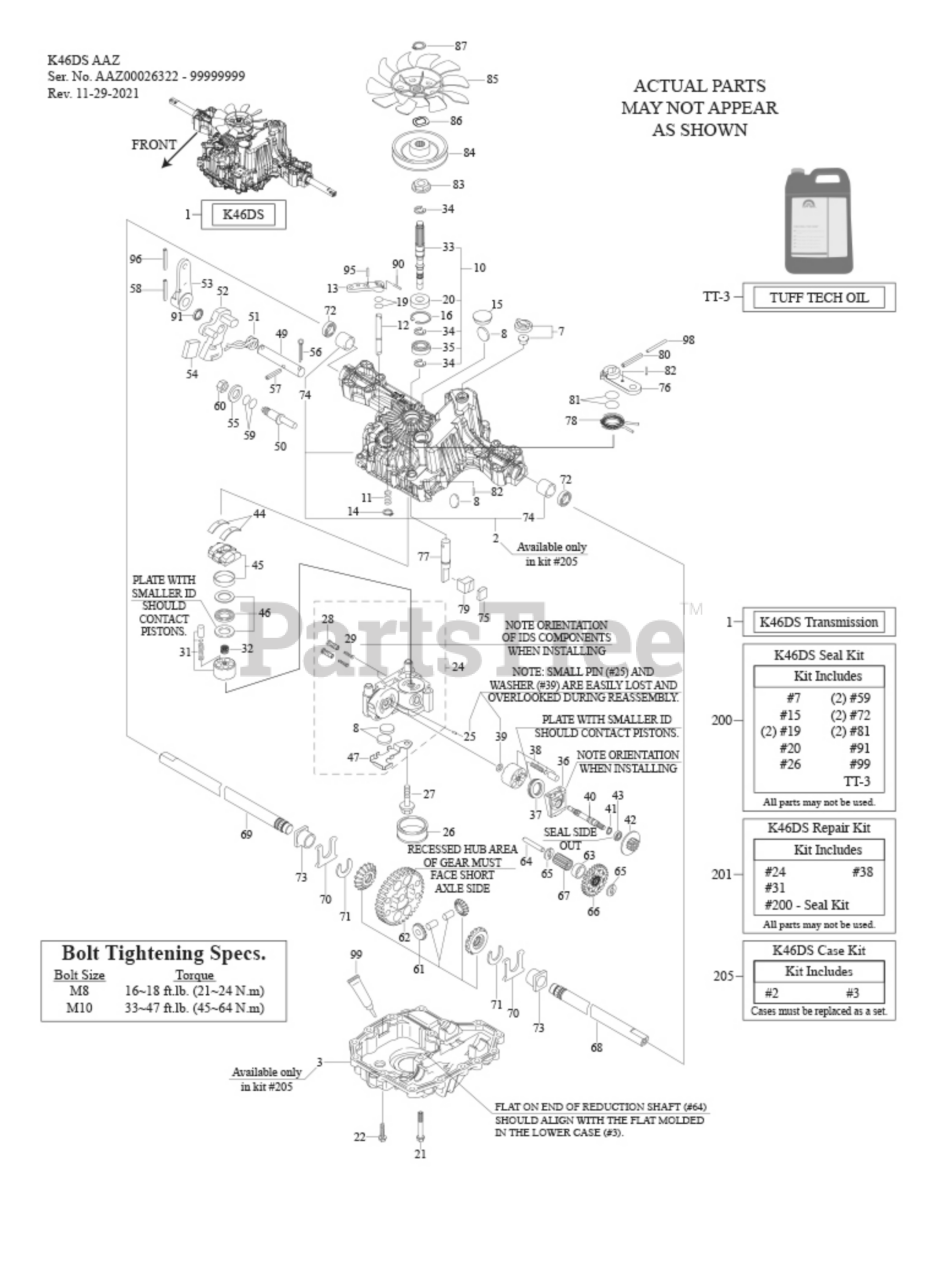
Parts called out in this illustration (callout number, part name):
1	TRANSMISSION ASSEMBLY
3	LOWER HOUSING (Not Available / Order Housing Kit)
7	VALVE ASSEMBLY-VENT
10	SHAFT KIT-PMP W/BRG
21	TAP SCREWPING 8X
22	TAP SCREWPING 8X
24	CENTER CASE
28	VALVE-IDS 1.2
31	BLOCK KIT-PISTON &
32	SPRING-CYL BLOCK
33	SHAFT-PUMP INPUT
35	BALL BEARING
36	HOUSING-MOTOR
37	THRUST BEARING MOTOR
38	BLOCK KIT-PISTON &
42	DISC-BRAKE W/MTR
44	BEARING-CRADLE THRUST
45	SWASHPLATE ASSEMBLY
46	BEARING ASSEMBLY-THRUST PM
47	HOLDER-MAGNET
49	SHAFT-CONTROL
51	TORSION SPRING
52	ARM-CONTROL A
53	LEVER-CONTROL F
55	FLAT WASHER 12
56	COTTER PIN 1/8 x .75
57	SPRING PIN 6 x 3
58	ROLL PIN 6 x 4
61	DIFFERENTIAL GEAR ASSEMBLY
62	FINAL GEAR 54T
63	FINAL PINION COLLAR
64	SHAFT-REDUCTION
65	THRUST WASHER
66	GEAR-REDUCTION
67	FINAL PINION GEAR 10T
68	AXLE SHAFT (LH)
69	AXLE SHAFT (RH)
70	THRUST WASHER
73	BUSHING-FLG AXL
78	SPRING-BRAKE RETUR
79	ACTUATOR-BRAKE
80	SPRING PIN 5 x 3
82	SPRING PIN 4 x 1
83	COLLAR-SPLINE
85	HYDRO FAN BLK
90	SPRING PIN 3 x 2
95	SPRING PIN 3 x 1
96	ROLL PIN 3.5 x 4
98	SPRING PIN 3 x 32
201	REPAIR KIT (W/OIL)
205	HOUSING KIT (UPPER/LOWER)
TT-3	TUFF TECH OIL 3 LITER BOTTLE
